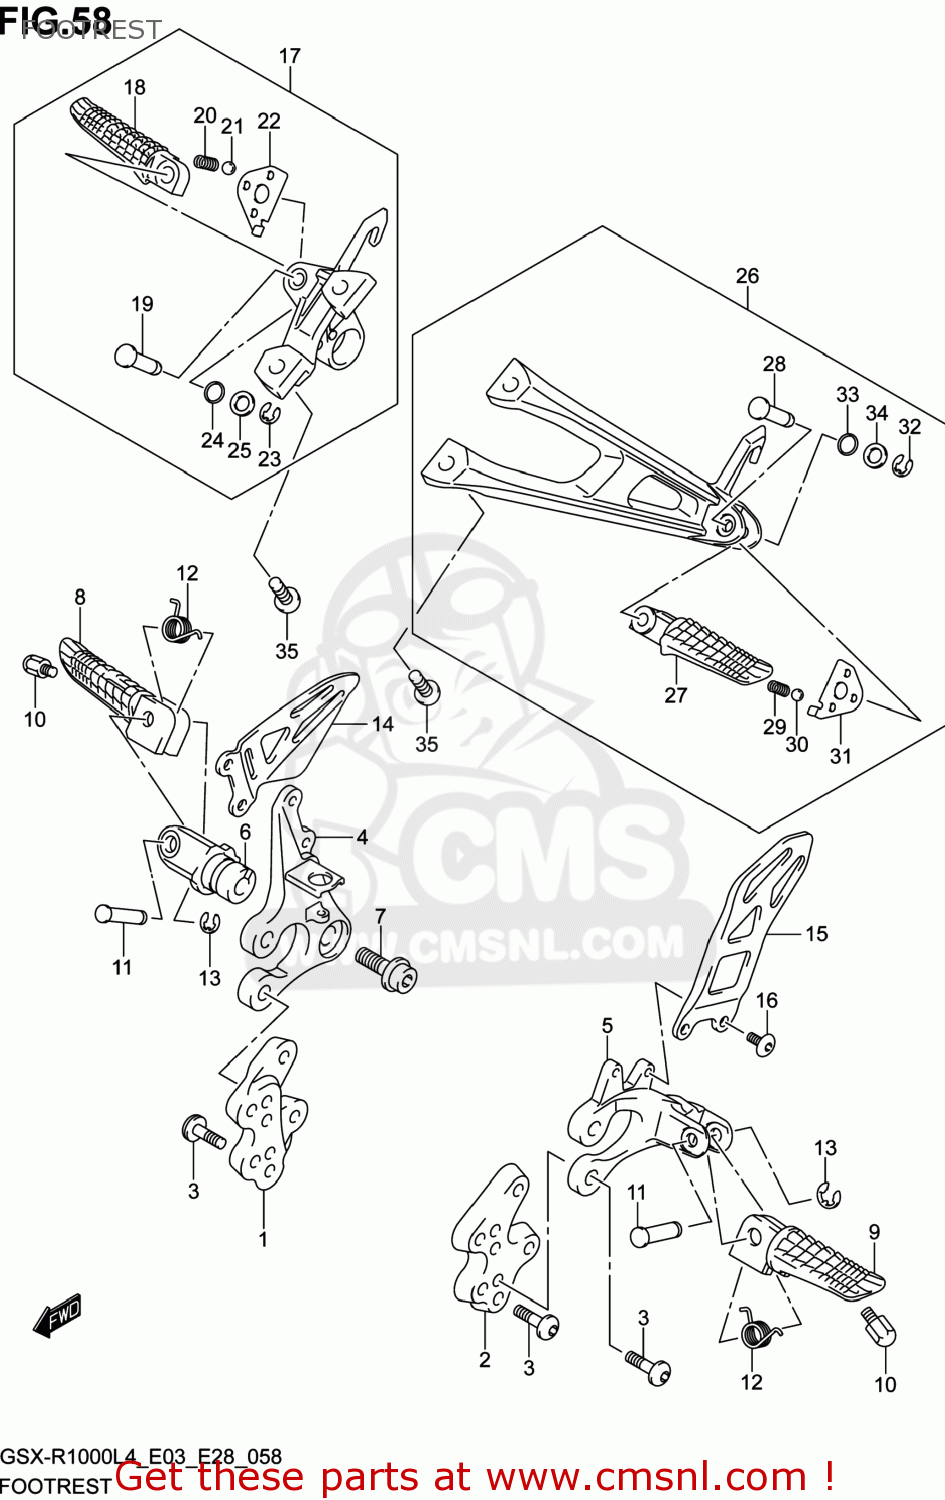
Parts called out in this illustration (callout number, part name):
1	BRACKET,FR FOOTREST NO.1,R
2	BRACKET,FR FOOTREST NO.1,L
3	BOLT(8X23)
4	BRACKET,FR FOOTREST NO.2,R
5	BRACKET,FR FOOTREST NO.2,L
6	HOLDER,FOOTREST
7	BOLT(10X28)
8	BAR,FR FOOTREST,R
9	BAR,FR FOOTREST,L
10	BOLT,BANK SENSOR
11	PIN
12	SPRING
13	E RING
14	GUARD,FR FOOTREST,R
15	GUARD,FR FOOTREST,L
16	SCREW,FOOTREST GUARD,L
17	FOOTREST ASSY,PILLION,R
18	BAR,PILLION FOOTREST,R
19	PIN
20	SPRING
21	BALL
22	PLATE,PILLION FOOTREST,R
23	E RING
24	O-RING
25	WASHER,PILLION FOOTREST
26	FOOTREST ASSY,PILLION,L
27	BAR,PILLION FOOTREST,L
28	PIN
29	SPRING
30	BALL
31	PLATE,PILLION FOOTREST,L
32	E RING
33	O-RING
34	WASHER,PILLION FOOTREST
35	BOLT(8X23)
